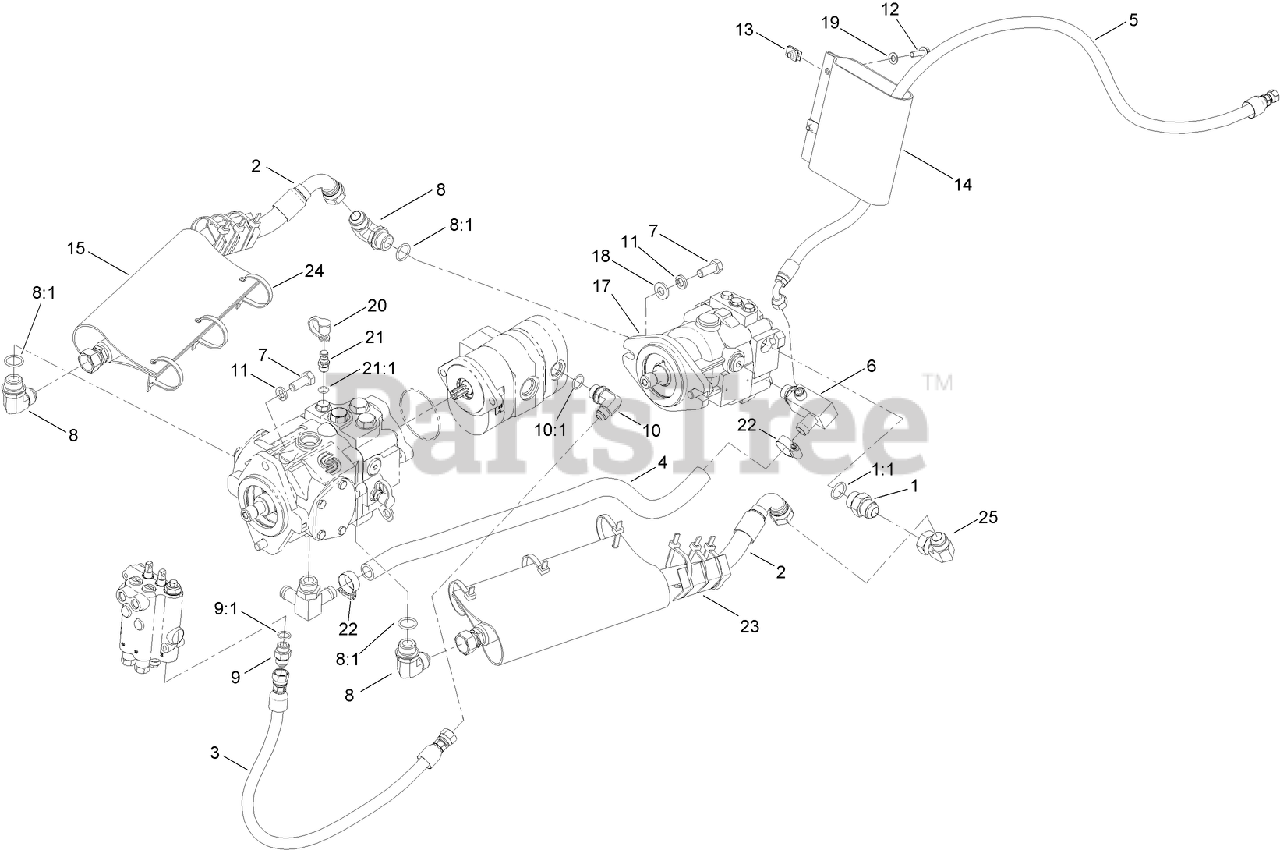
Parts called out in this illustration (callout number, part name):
1	FITTING-STRAIGHT
1:1	O-RING
2	HOSE (PUMP TO REG VALVE)
3	HOSE ASM
4	HOSE ASM
5	HOSE ASM
6	FITTING-90 DEG (SPECIAL)
7	SCREW-HH
8	FITTING-ELBOW, 90 DEG
8:1	O-RING
9	FITTING-STRAIGHT
9:1	O-RING
10	FITTING-90 DEG
10:1	O-RING
11	WASHER-LOCK
12	SCREW-HHF
13	NUT-CLIP, U
14	BOOT-HOSE
15	BOOT-HOSE
17	HYD PISTON MOTOR ASM
19	WASHER-PLAIN
20	CAP-DUST
21	FITTING-DIAGNOSTIC
21:1	O-RING
22	CLAMP-HOSE
23	PROTECTOR-HOSE
24	TIE-CABLE
25	FITTING-ELBOW, 90
